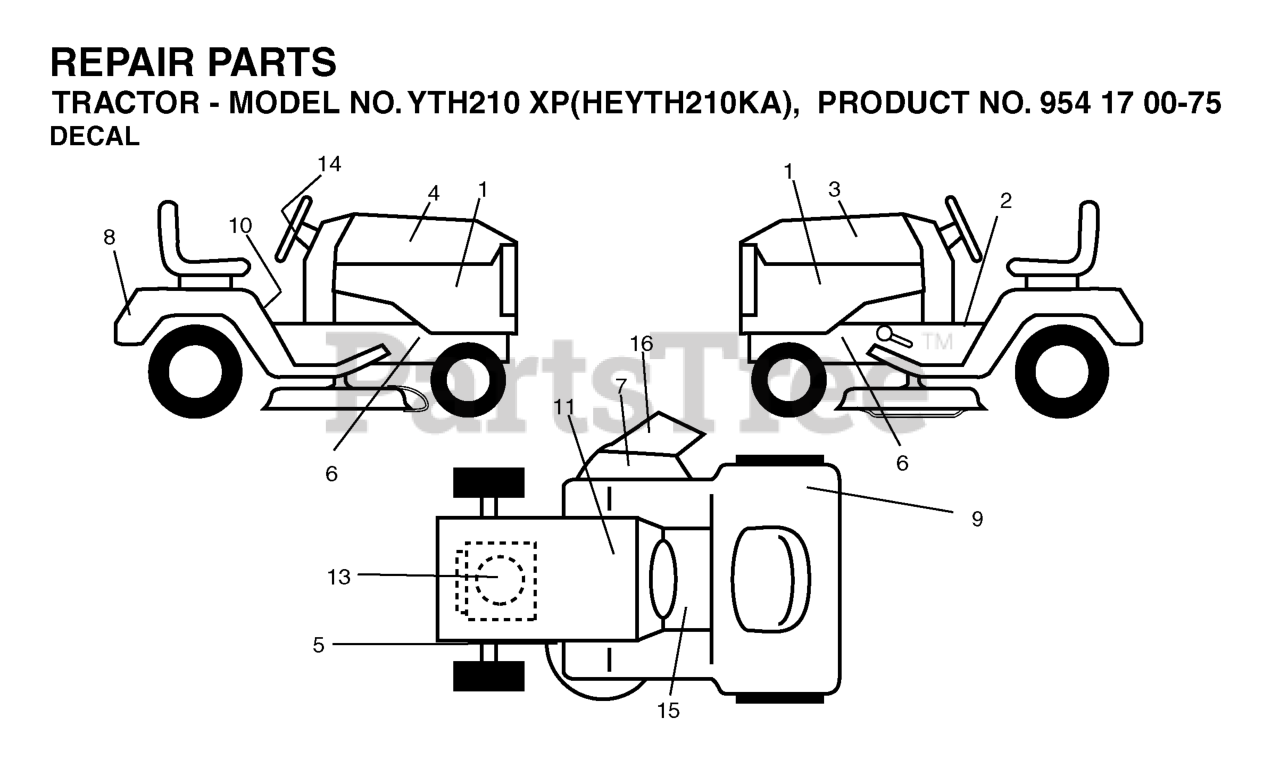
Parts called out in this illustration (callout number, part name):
2	DECAL PARK BRAKE
5	DECAL V BELT SCHEMATIC
7	DECAL.INTERNATIONL.CUTFINGER
8	DECAL FENDER HUSQ
9	Decal, Fender 100 DB/CE
10	DECAL READ OWNER'S MAN SYMS
11	DECAL BTRY SYMBOLS
14	DECAL.WHEEL.STEERING.HUSQ.PERM
15	DECAL
16	DECAL DECK "B" 42"
